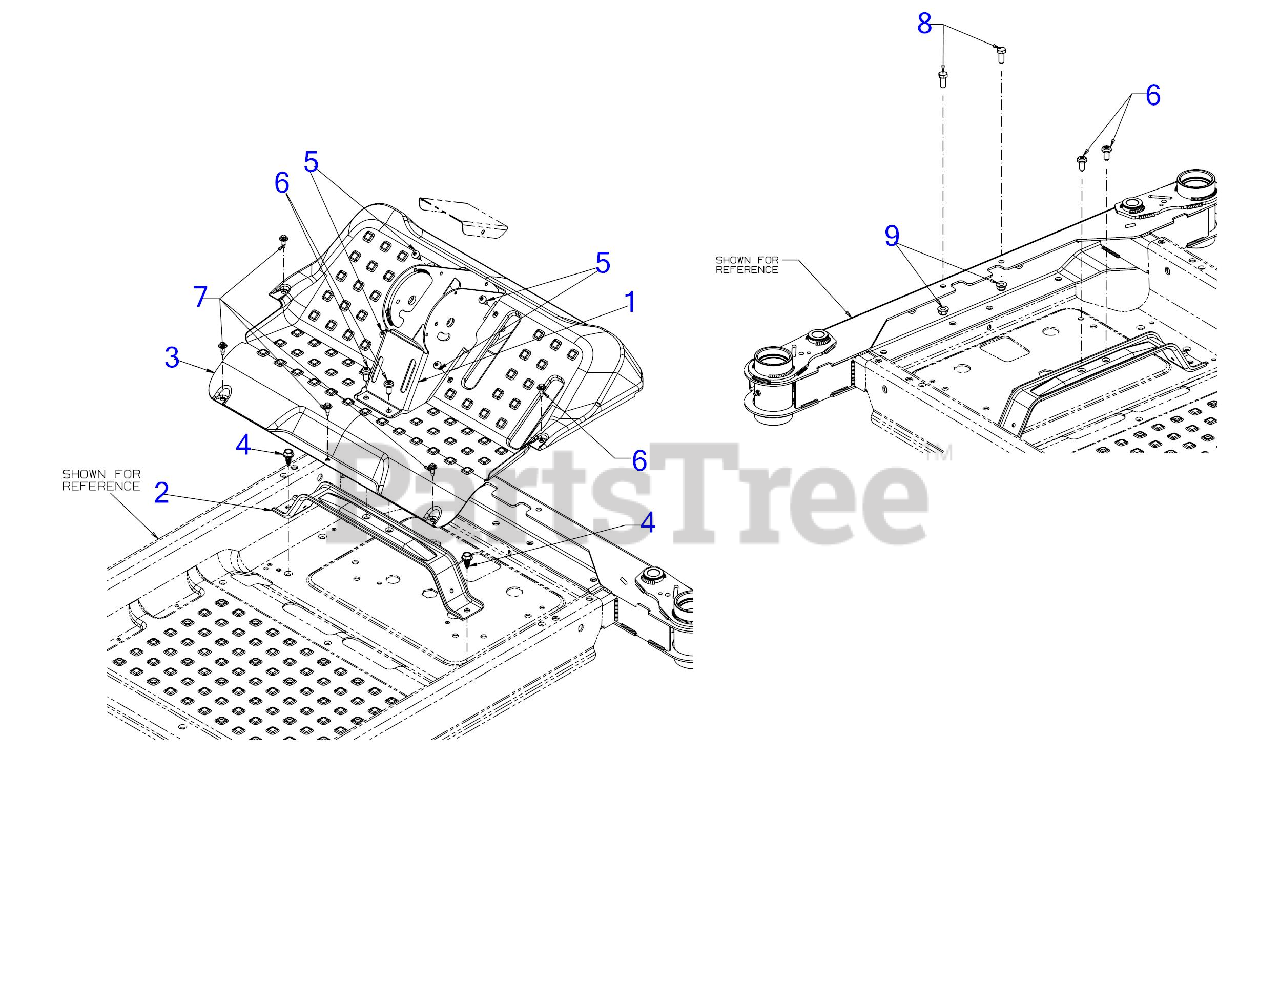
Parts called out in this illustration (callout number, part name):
4	SCREW 5/16-18 x .750
5	SCREW 1/4-20 x .5
6	SCREW 5/16-18 x .750
7	SCREW M6-1 x .625
8	SCREW 5/16-18 x .75 GR5
9	FLANGE LOCK NUT 5/16-18
